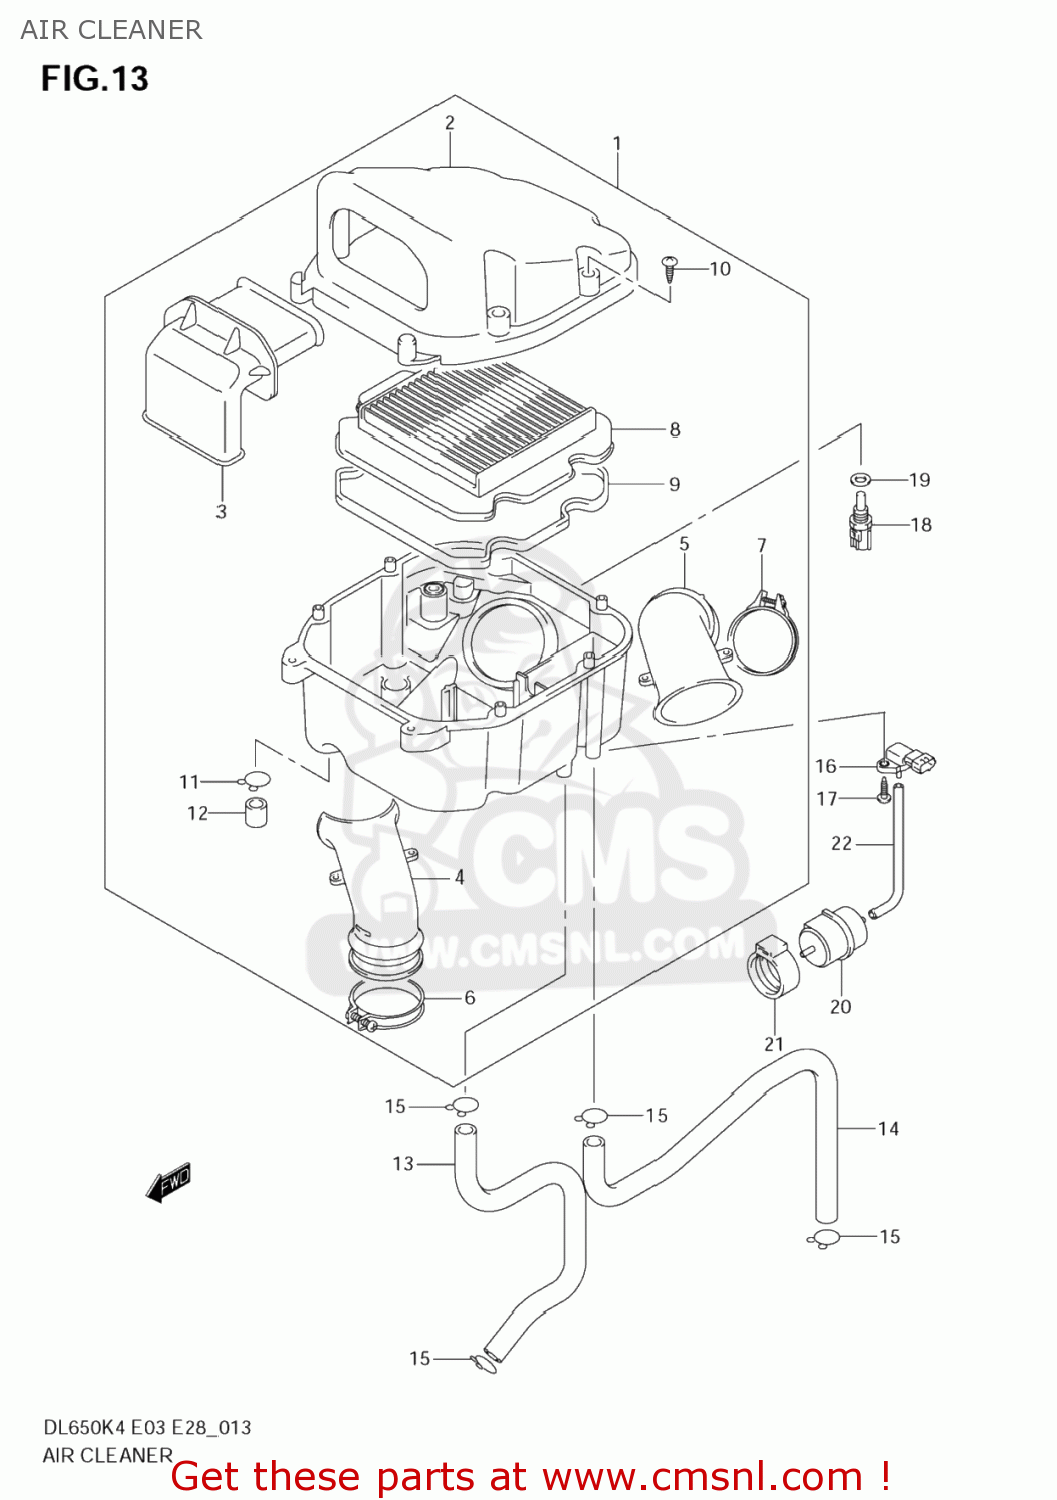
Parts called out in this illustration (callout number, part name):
1	CLEANER ASSY,AIR
2	CAP,AIR CLEANER
3	TUBE,INLET
4	TUBE,OUTLET A
5	TUBE,OUTLET B
6	CLAMP
7	CLAMP
8	FILTER,AIR CLEANER
9	GASKET,AIR CLEANER (NAS)
10	SCREW
11	PLUG
12	CLIP
13	TUBE,BREATHER CYLINDER
14	TUBE,BREATHER CRANKCASE
15	CLIP
16	SENSOR COMP,BO
17	SCREW
18	SENSOR,WATER TEMP
19	GASKET(12X17X1) (NAS)
20	CHAMBER,VACUUM
21	BAND,VACUUM CHAMBER
22	HOSE(3.5X7.5X600)
